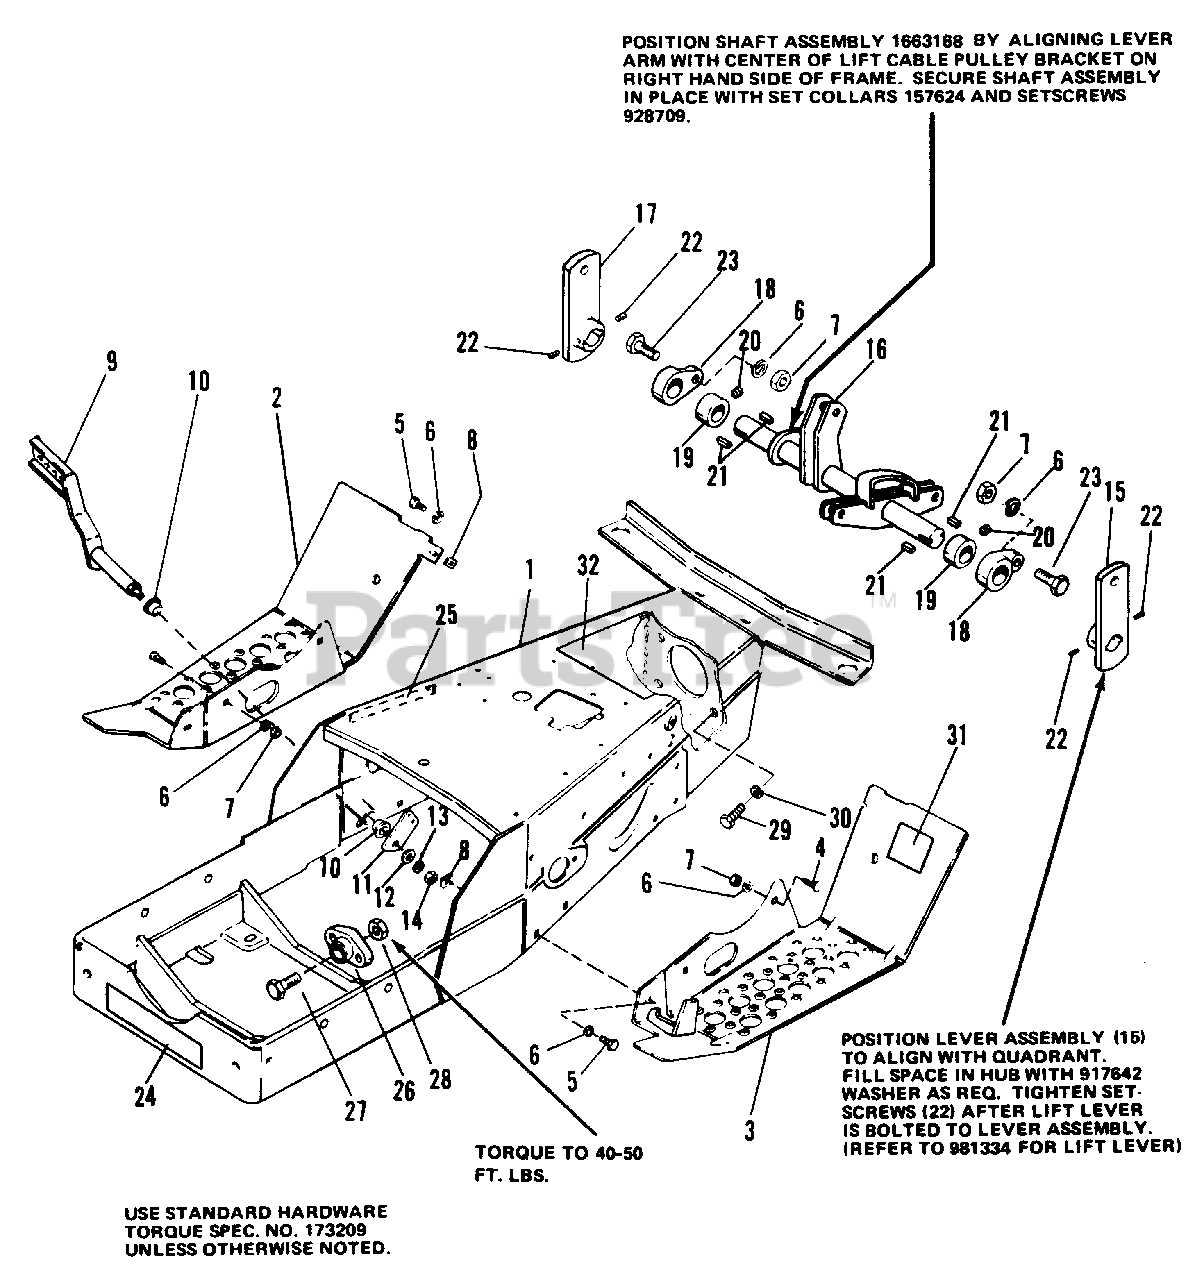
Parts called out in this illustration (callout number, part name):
1	REAR FRAME ASSEMBLY
2	FOOT REST, R.H.
3	FOOT REST, L.H.
4	BOLT, Carriage, 5/16-18 x 3/4
5	CAPSCREW, Hex Hd., 5/16-18 x 3/4
6	LOCKWASHER, 5/16
7	NUT, Hex, Full, 5/16-18
8	NUT, Speed, Tinn., 5/16-18
9	FOOT PEDAL ASSEMBLY
11	ARM, Pedal Foot
12	WASHER, 3/8
13	LOCKWASHER, 3/8
14	NUT, Hex, Full, 3/8-16
15	FRONT LIFT LEVER ASSEMBLY
16	LIFT SHAFT ASSEMBLY
17	LIFT LEVER ASSEMBLY
18	BEARING, Lift Lever
19	SET, Collar
20	SETSCREW, Cup Pt., 5/16-18 x 3/8
22	SETSCREW, Soc. Hd., 5/16-18 x 1/4
23	CAPSCREW, Hex Hd., 5/16-18 x 1-1/4
24	DECAL, Simplicity
25	DECAL, Clutch
26	BEARING, Pivot
27	CAPSCREW, Whiz, 3/8-16 x 1-1/4
28	NUT, Flange, 3/8-16
29	CAPSCREW, Hex Hd., 7/16-14 x 1-1/2
30	LOCKWASHER, 7/16
31	DECAL, Parking Brake
32	DECAL, Shift Pattern
